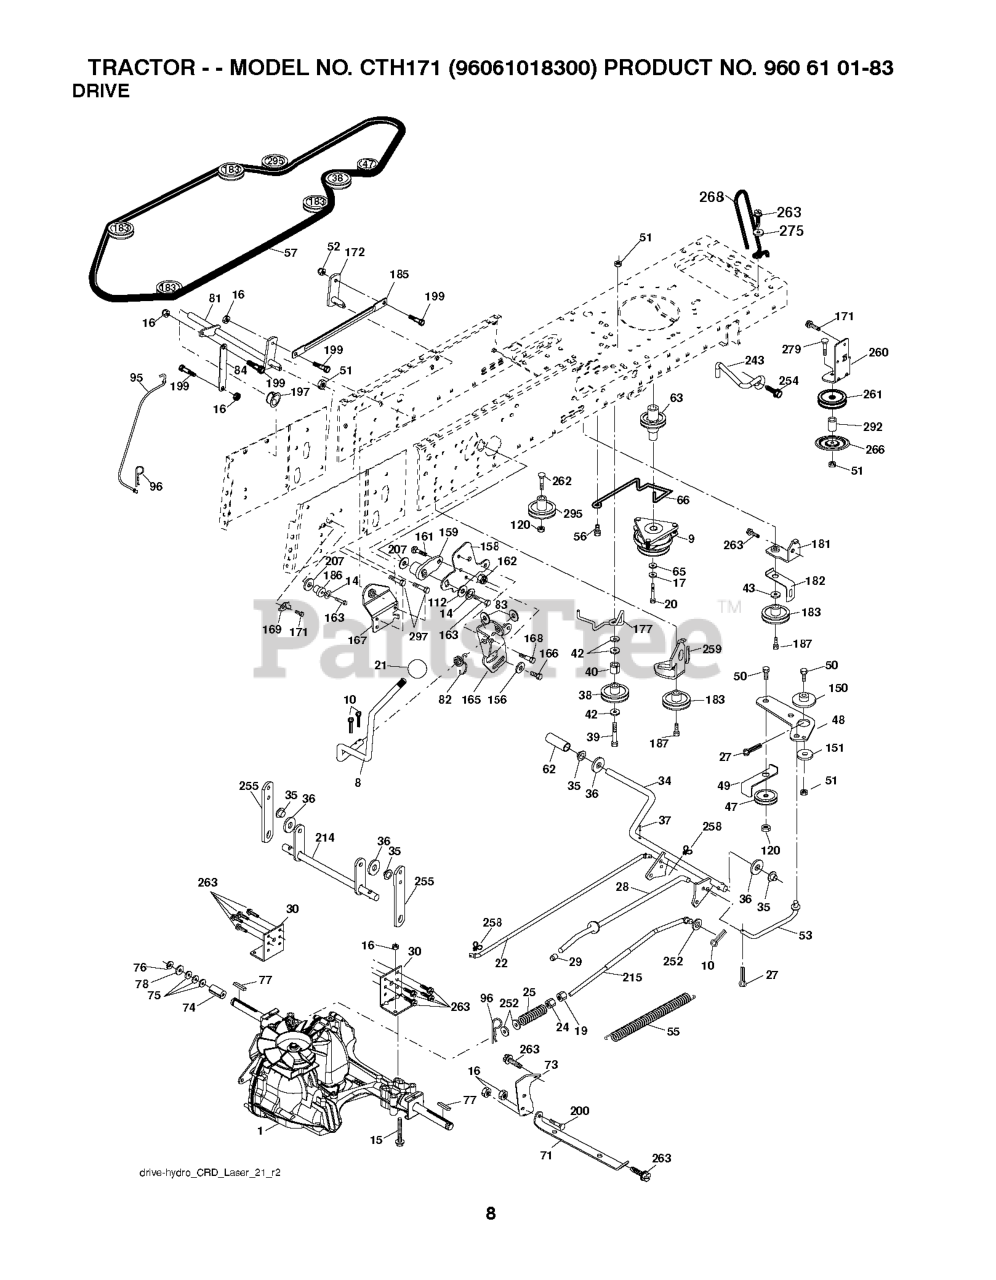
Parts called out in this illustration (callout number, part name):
8	ROD SHIFT FENDER ADJUST LT
10	PIN COTTER
14	LOCKWASHER
15	BOLT HEX 5/16-18 GR 5
16	NUT.71038.31-18.HEX.NYLOCK
19	NUT
20	BOLT HEX 7/16-20X4-1/4"
21	KNOB.DUCKHEAD.1/2
22	ROD
24	NUT
25	SPRING BRAKE ROD
27	COTTER PIN
28	ROD, PARKING BRAKE
29	CAP
30	BRKT, TRNSXLE MNT 20"
34	SHAFT, FOOT PEDAL
35	BEARING.NYLON
37	DRIVE PIN
38	PULLEY.FLAT
42	WASHER
47	IDLER PULLEY
48	BELLCRANK, CLUTCH
49	RETAIN BELT
50	BOLT.3/8-16X1.50
52	LOCKNUT
53	LINK.CLUTCH.7.66.2005
55	SPRING, RETURN LT
56	SCREW.3/8-16
57	V-BELT 113"
62	PEDAL COVER T
63	PULLEY.ENGINE.CVX.LT
65	LOCKWASHER
66	KEEPER BELT ENGINE
71	STRAP TORQUE RH HYDRO
73	STRAP TORQUE LH HYDRO
74	SPACER AXLE
77	SQUARE KEY
81	ASM.CROSS.SHAFT.REAR.CRD.0510
82	SHIFT SPRING
83	WASHER
84	LINK.PNT.TRANSAXLE.0510.CRD
95	LINK
96	RETAINER M
120	NUT LOCK FLG 3/8-16 UNC
150	BUSHING.BELLCRANK.GRD.DR
151	WASHER 12/32X2X10GA
156	WASHER.SRRTD.5/16
158	BRACKET
159	RB HUB.SHIFT
161	BOLT
162	NUT.CROWNLOCK.1/4
165	RP BRACKET
166	CAPSCREW.HXHD.FLG.5/16-18X.625
167	BRACKET.SUPT.SHIFT.CRD
168	BOLT.SHOULDER.5/16-18X
169	PLATE.FASTENING.CROSS.SHAFT
172	LINK
181	BRACKET
182	BELT GUIDE
183	PULLEY.V-IDLER.GRND.DR
185	LINK
186	HUB.TAPERED.ROUND.CRD
187	BOLT.5/16-18X1.25
197	NYLINER SNAP 5/8" ID
199	BOLT SHOULDER 5/16-18 UNC
207	WASHER NYL
214	LEVER
215	ROD
243	BRACKET, ANTI-ROTATION
252	WASHER
254	SCREW 3/8-16X1
255	SHAFT
258	CLIP RETAINER
259	BRACKET
261	FLAT IDLER PULLEY
263	SCREW, 3/8-16X3/4
266	PROTECTOR
268	GUARD MUFFLER
275	WASHER
292	SPACER
295	PULLEY IDLER COMPOSITE
